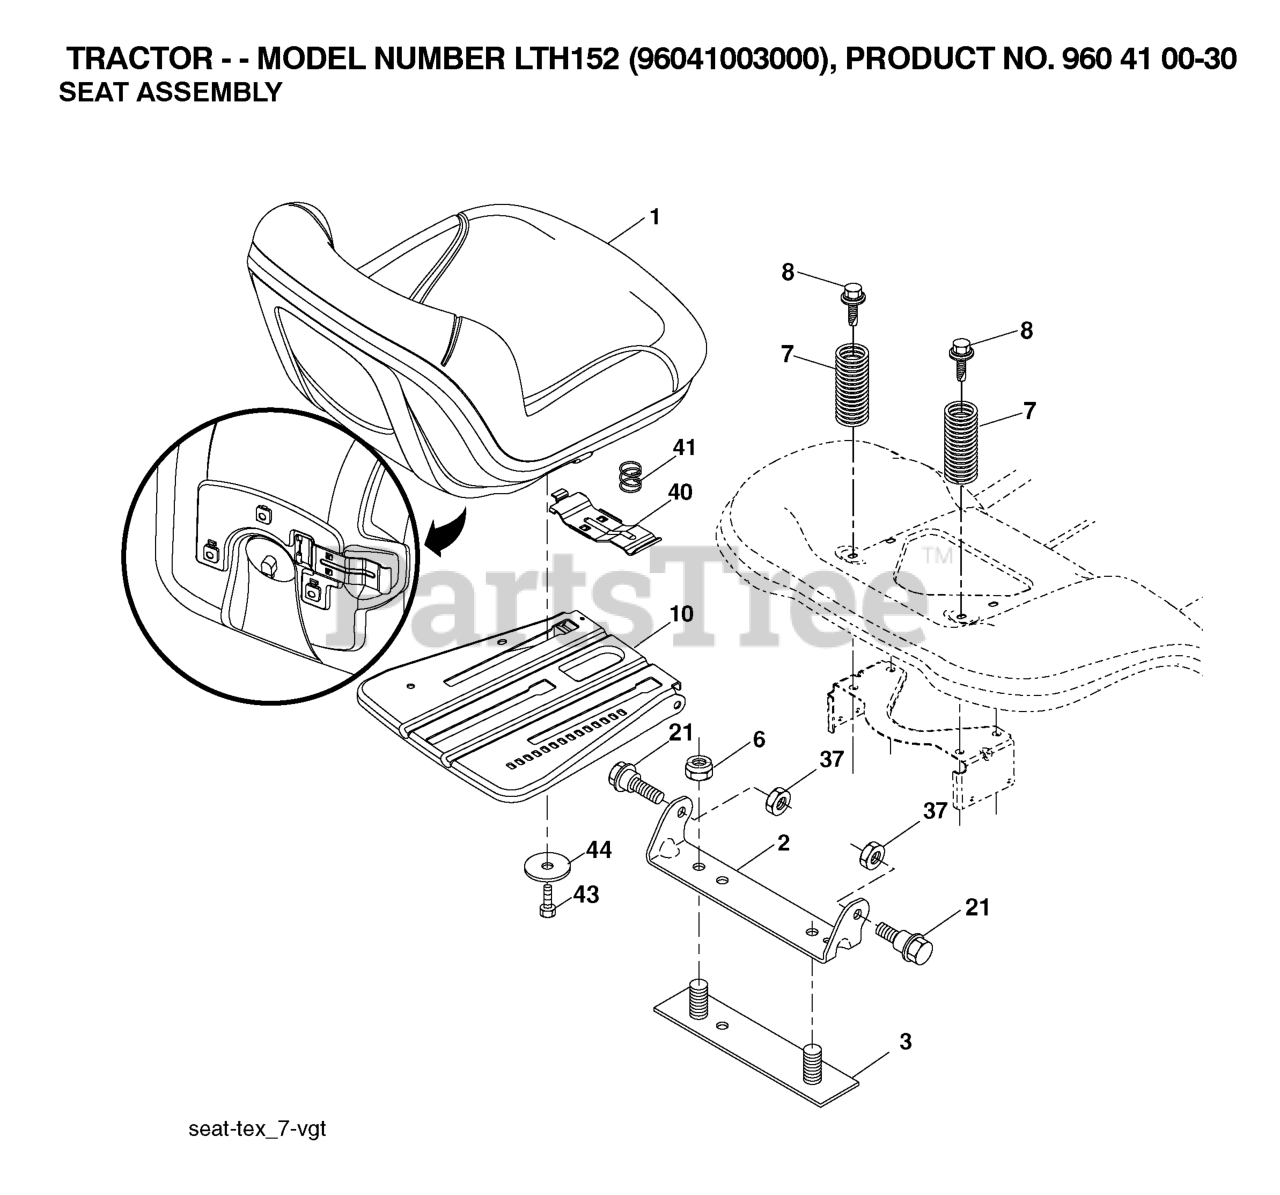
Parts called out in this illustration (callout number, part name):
1	SEAT.TH130.GRY.MILSCO.
2	BRKT.PIVOT.FENDER
3	STRAP
6	NUT
7	SPRING COMPRESSION
8	BOLT.5/16-18UNCX3/4 W/SEMS.BLK
10	PAN.ASM.SEAT.3PT
21	BOLT.SHOULDER.5/16-18
37	NUT.71038.31-18.HEX.NYLOCK
40	HANDLE.SLIDE.SEAT.TEX.BLACK
41	SPRING.LATCH.SEAT.TEX
44	WASHER 13/32 X 2-3/8 X 12GA
